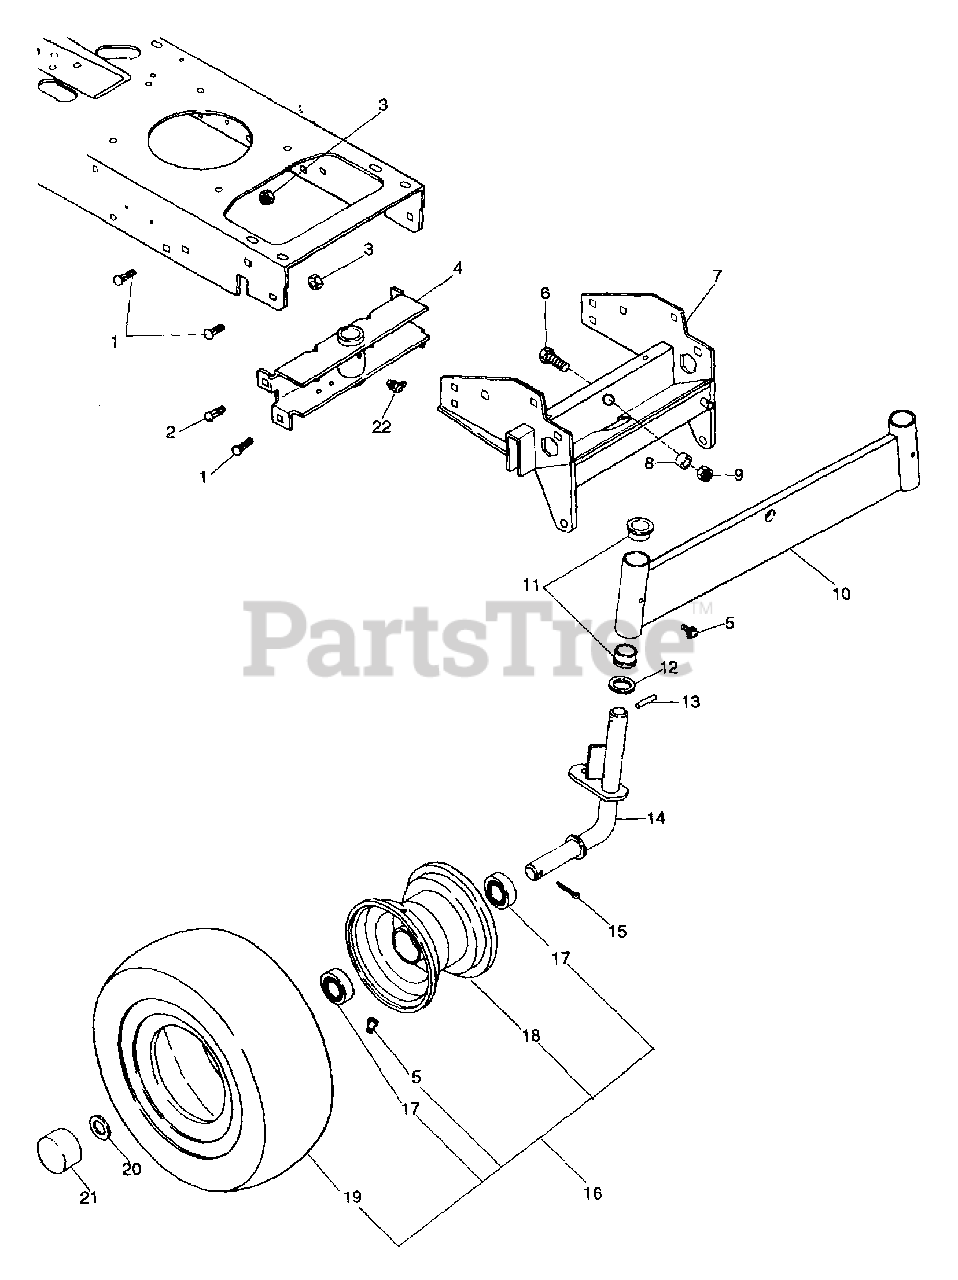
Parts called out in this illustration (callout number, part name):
1	BLT-RDHDSQNK .38-16X.75 SHT PL
2	BLT-RDHDSQSHNK .38-16X1.00 PL
3	NUT-LK-FLG .375-16 PL
4	PIVOT CHANNEL
5	SPIN DRIVE ZERK FITTING
6	BLT-HEX .50-13X1.50 PL GR5
7	FRONT AXLE SUPPORT
8	SPACER .531X.748X.524
9	NUT-LK-CROWN .50-13 GR C PL
10	FRONT AXLE
11	BSHG-FLG 1.000X1.25X.75X1.50
12	WSHR-FL-STL 1.010X1.505X.062PL
13	PIN-ROLL .250X1.38
14	LH SPINDLE
14	RH SPINDLE
15	PIN-COTR .25X1.50 ST PL
16	T/WHL ASSY 15 X6-6
17	BRG-BALL 1.0X2.0X.55
20	WSHR-FL-STL 1.015X1.500X.125
21	FRONT HUB CAP
22	SPIN DRIVE ZERK FITTING 90
